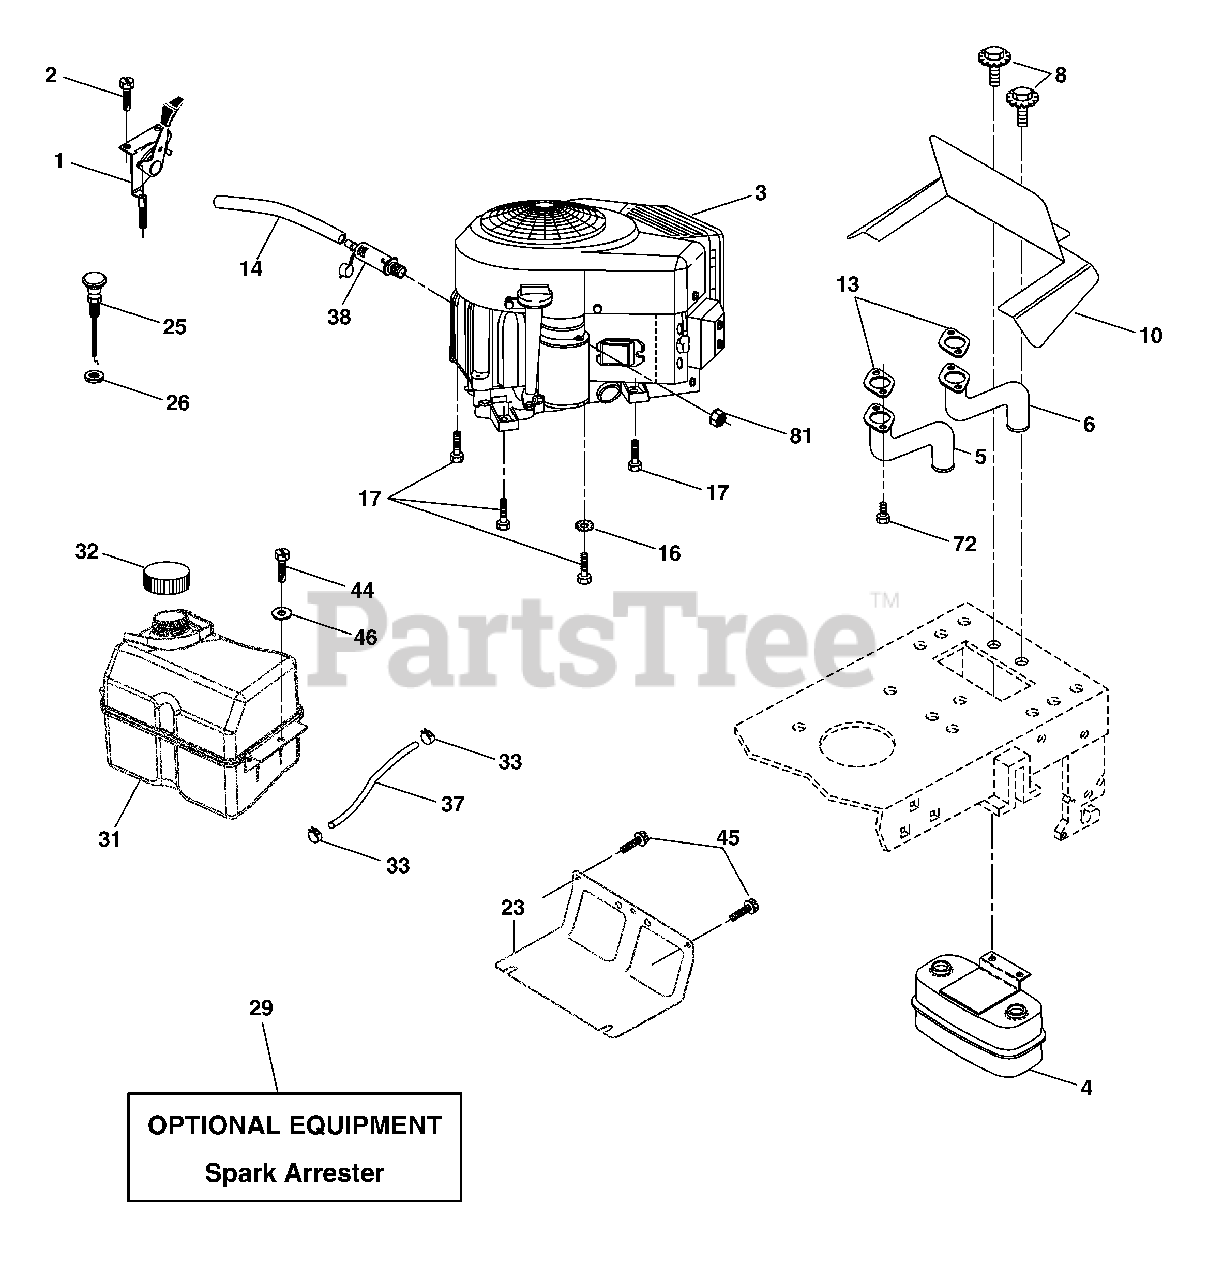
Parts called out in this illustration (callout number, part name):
1	Control, Throttle
2	Screw Hex Thd Cut 1/4-20 x 1/2
4	Muffler, Asm. Twin Lo-Tone
5	Pipe Exhaust Intek 20 RH
6	Pipe Exhaust Intek 20 LH
8	Bolt 5/16-18 UNC x 3/4 w/Sems
10	Shield Browing B&S Intek II
13	Muffl er Gasket
14	Tube Oil Drain
16	Washer, Lock Ext tooth 3/8
17	Screw 3/8-16 x 1-1/2
23	Shield, Browning/Debris Guard
25	Control Choke
26	Nut Keps 3/8-24 UNF
29	Arrester, Spark
31	Tank, Fuel
32	Cap Gauge, Fuel
33	Clamp, Hose Blk
37	Line, Fuel 7.5
38	Plug Drain Oil Easy
44	Screw Hex Wsh Thdrol 1/4-20 x 3/4
45	Screw Hex Wsh Thdrol 3/8-16 x 3/4
46	Washer 9/32 x 7/8 x 16 Ga.
72	Screw Socket Head 5/16-18 x 1
81	Nut Keps Hex 1/4-20 Unc
